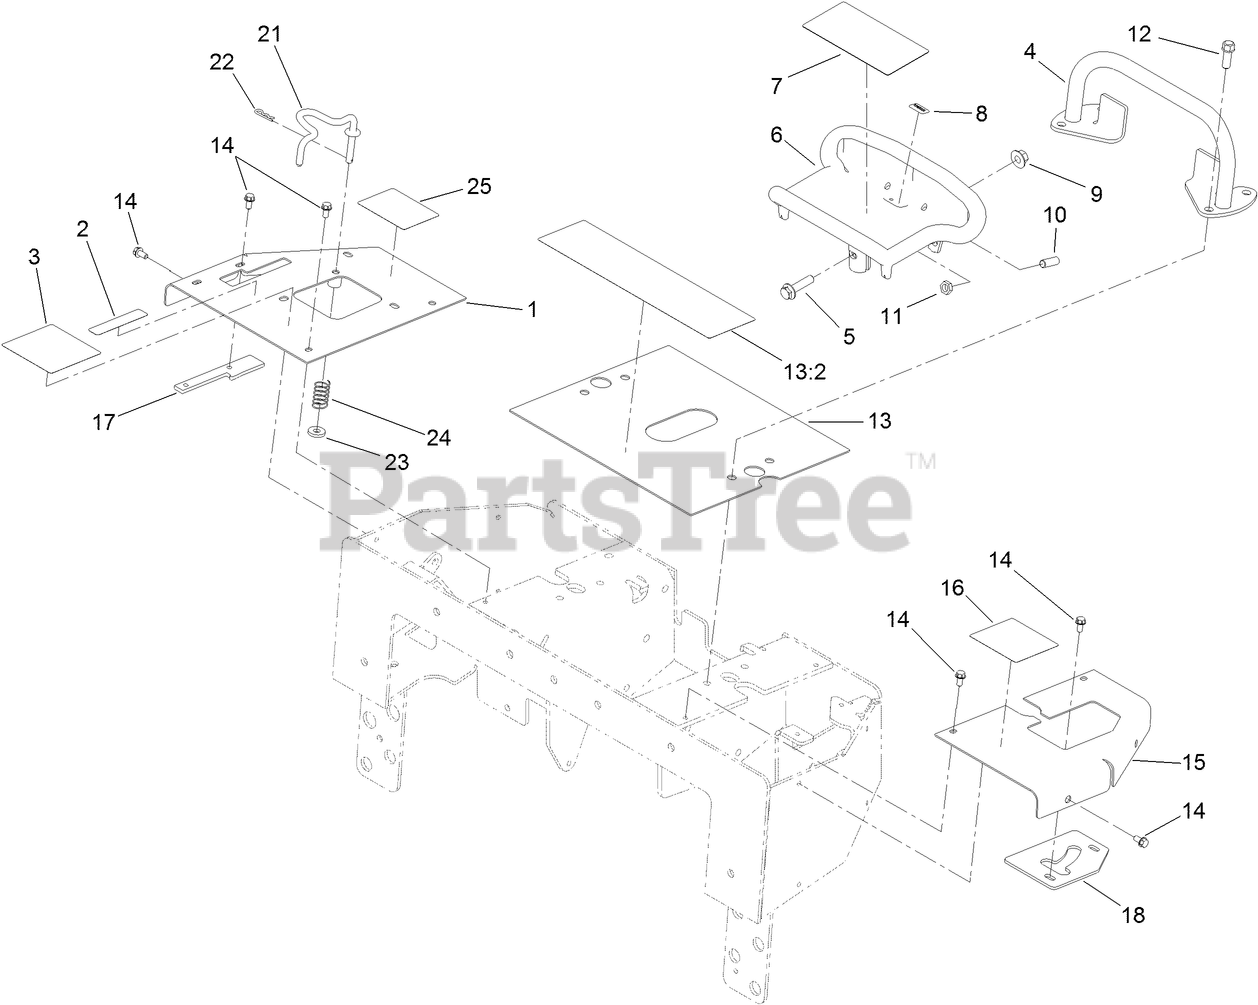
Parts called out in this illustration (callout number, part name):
1	PANEL-RH
2	DECAL-BRAKE
3	DECAL-CONTROL, LOADER
4	BAR-REFERENCE
5	SCREW-HHF
6	HANDLE-CONTROL
7	DECAL-TRACTION
8	DECAL
9	NUT-FLANGE
10	SCREW-SET
11	NUT-JAM
12	SCREW-TAPTITE
13	CENTER PANEL ASM
13:2	DECAL-DANGER
14	SCREW-HWH
15	PANEL-LH
16	DECAL-CONTROL, AUXILIARY
17	PLATE-LOCKING, BRAKE
18	PLATE-STOP
21	ROD-INTERLOCK
22	PIN-COTTER
23	WASHER-FLAT
24	SPRING-CONTROL
25	DECAL-LOADER LOCK
